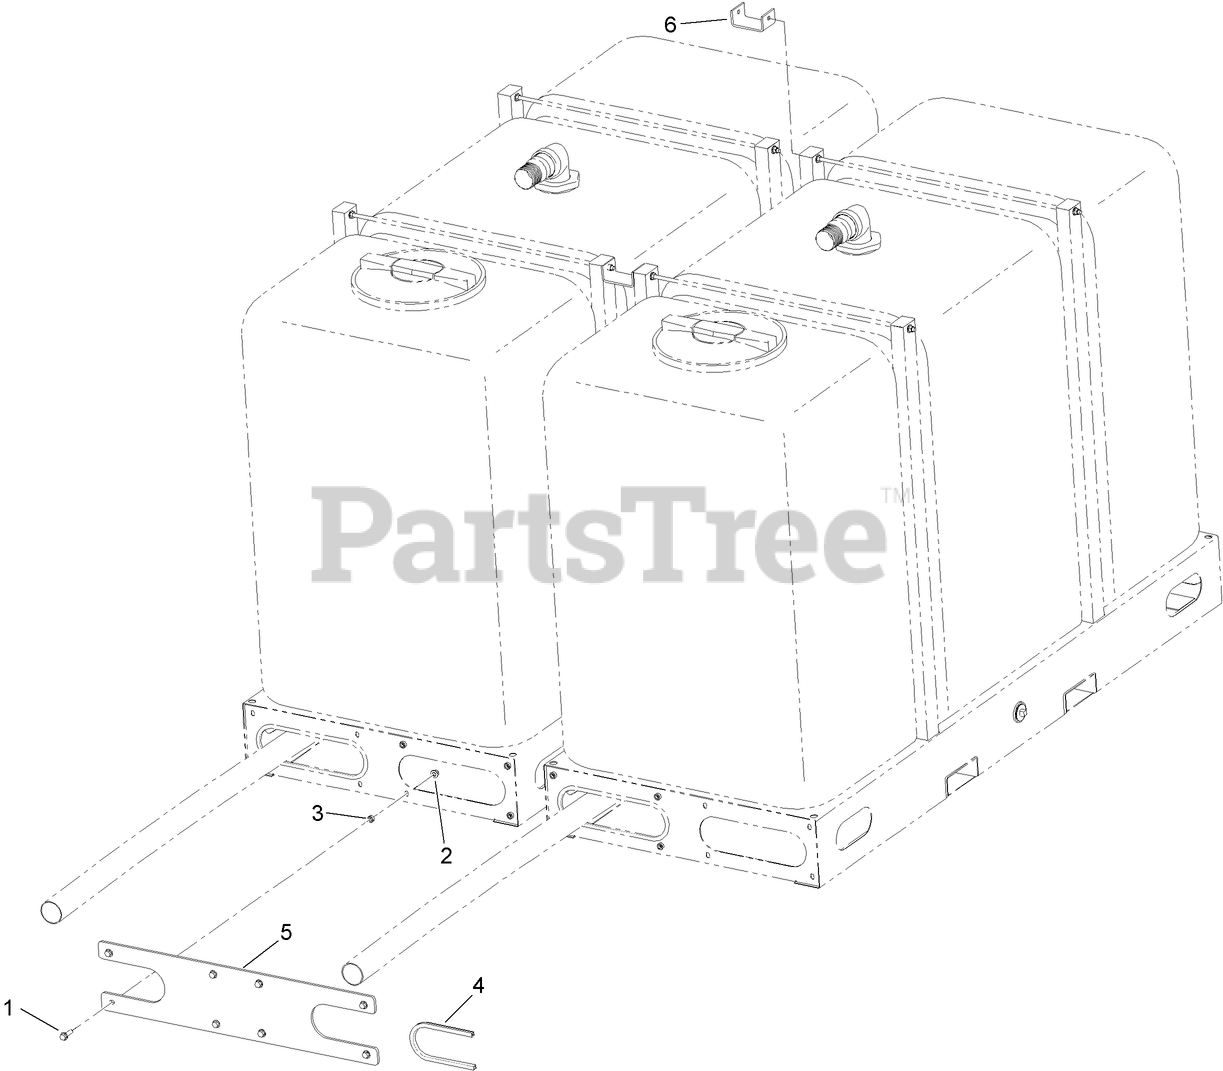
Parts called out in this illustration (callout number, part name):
1	SCREW-HHF
2	NUT-LOCK
3	SPACER
4	TRIM-PLATE
5	PLATE-FRAME
6	PLATE-CONNECTOR
